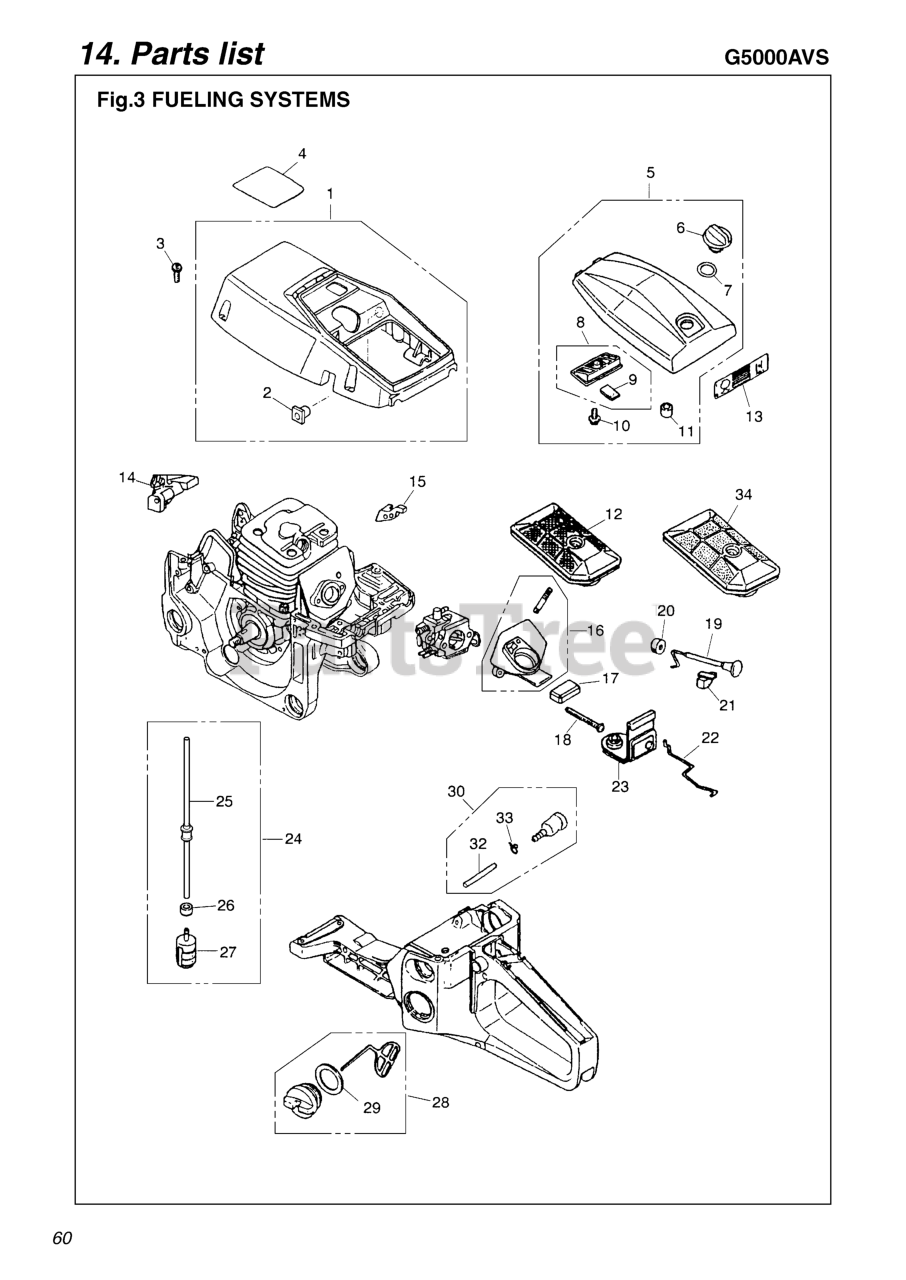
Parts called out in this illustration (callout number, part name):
1	CYLINDER COVER
3	SCREW (REPLACES 2616-24320)
5	COVER COMP (RPLS -83304)
7	GASKET, KNOB
8	CLEANER COMP
10	SCREW
12	CLEANER, AIR
16	MANIFOLD COMPLETE
17	SUPPORTER
19	ROD, CHOKE
21	GUIDE
22	ROD, THROTTLE
24	PIPE ASSY. (RPLS. -8536)
25	PIPE (REPLACES -85R5)
27	FILTER ASSY
28	CAP ASSEMBLY
29	GASKET
30	BREATHER ASSEMBLY
33	CLIP (REPLACES 2841-31280)
34	CLEANER, AIR (FLOCKED)
